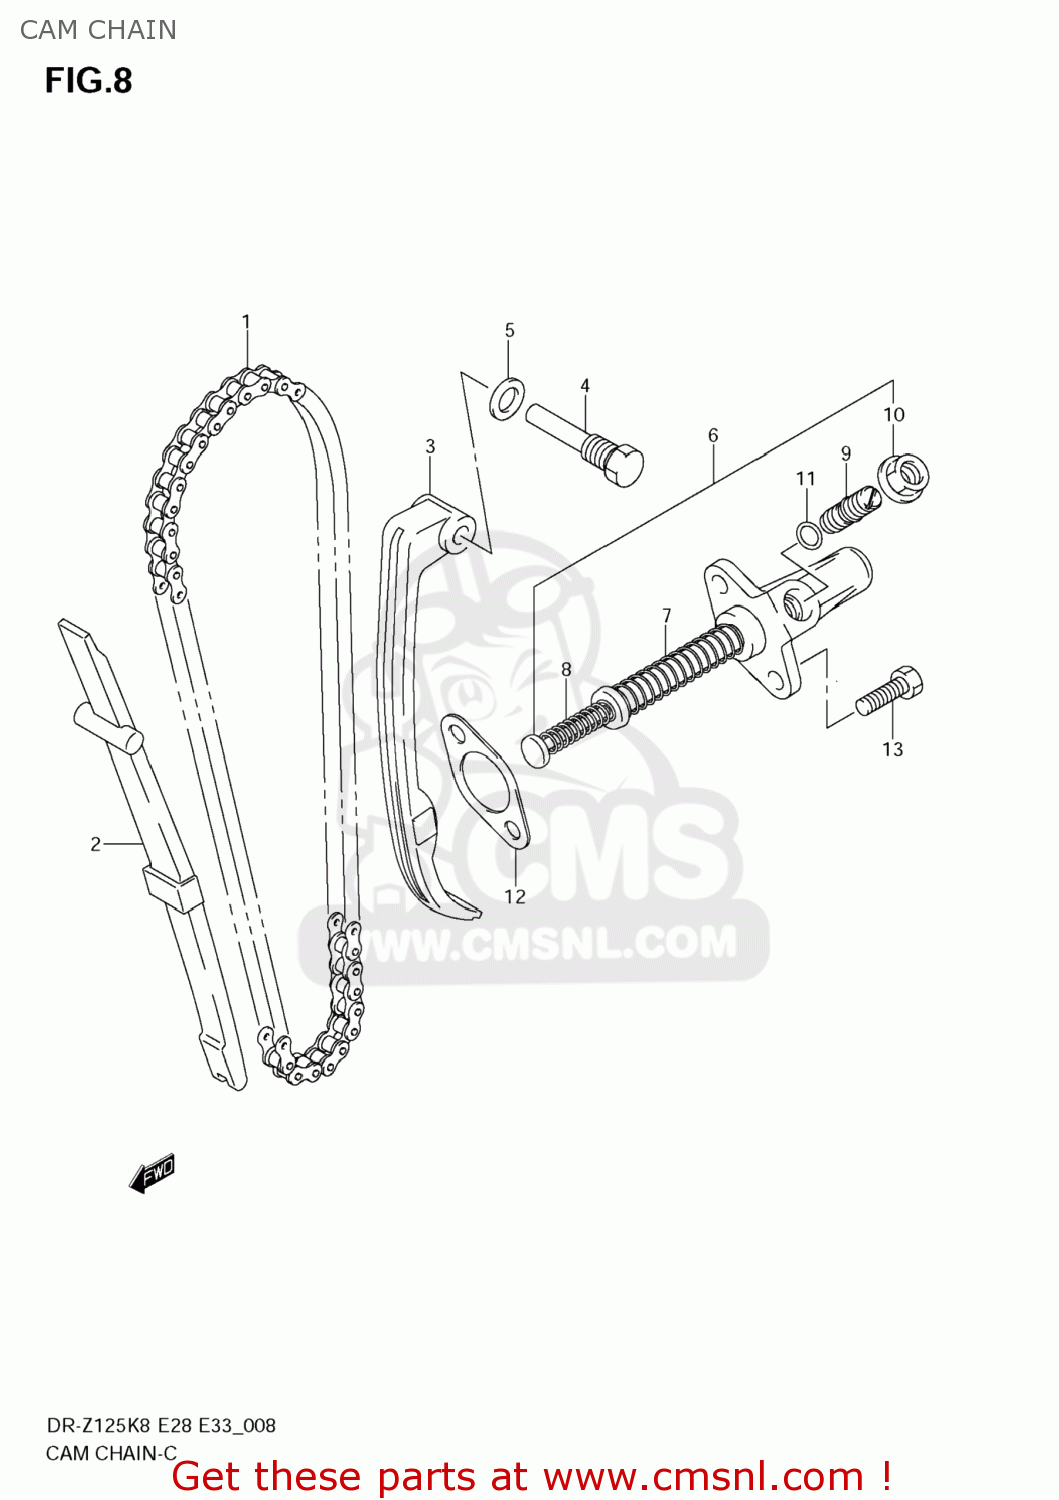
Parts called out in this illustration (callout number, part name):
1	CHAIN,CAMSHAFT DRIVE
2	GUIDE,CAM CHAIN
3	TENSIONER,CAM CHAIN
4	BOLT,CAM CHAIN TENSIONER
5	GASKET(8.2X14X1) (NAS)
6	ADJUSTER ASSY,TENSIONER
7	SPRING
8	SPRING
9	BOLT,ADJUST
10	NUT
11	O RING(D:1.9,ID:5.7)
12	GASKET,TENSIONER ADJUSTER (NAS)
13	BOLT
